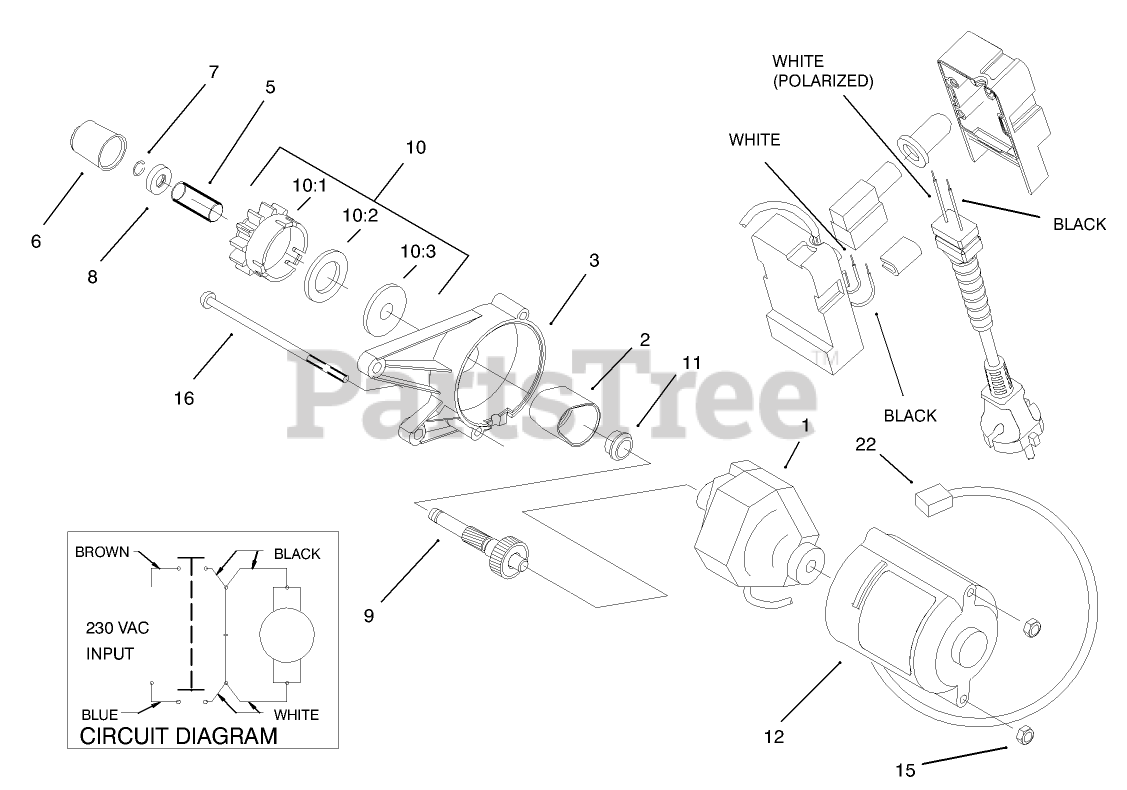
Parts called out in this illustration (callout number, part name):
2	COVER-GEAR
3	HOUSING-UPPER, STARTER
5	SPRING
6	CAP-PINION
7	RING-LOCK
8	STOP-PINION
10	PINION ASM
10:2	PINION
10:3	RING-RUBBER
11	BUSHING
12	HOUSING-LOWER, STARTER
15	NUT-LOCK, NI
22	TIE-CABLE
